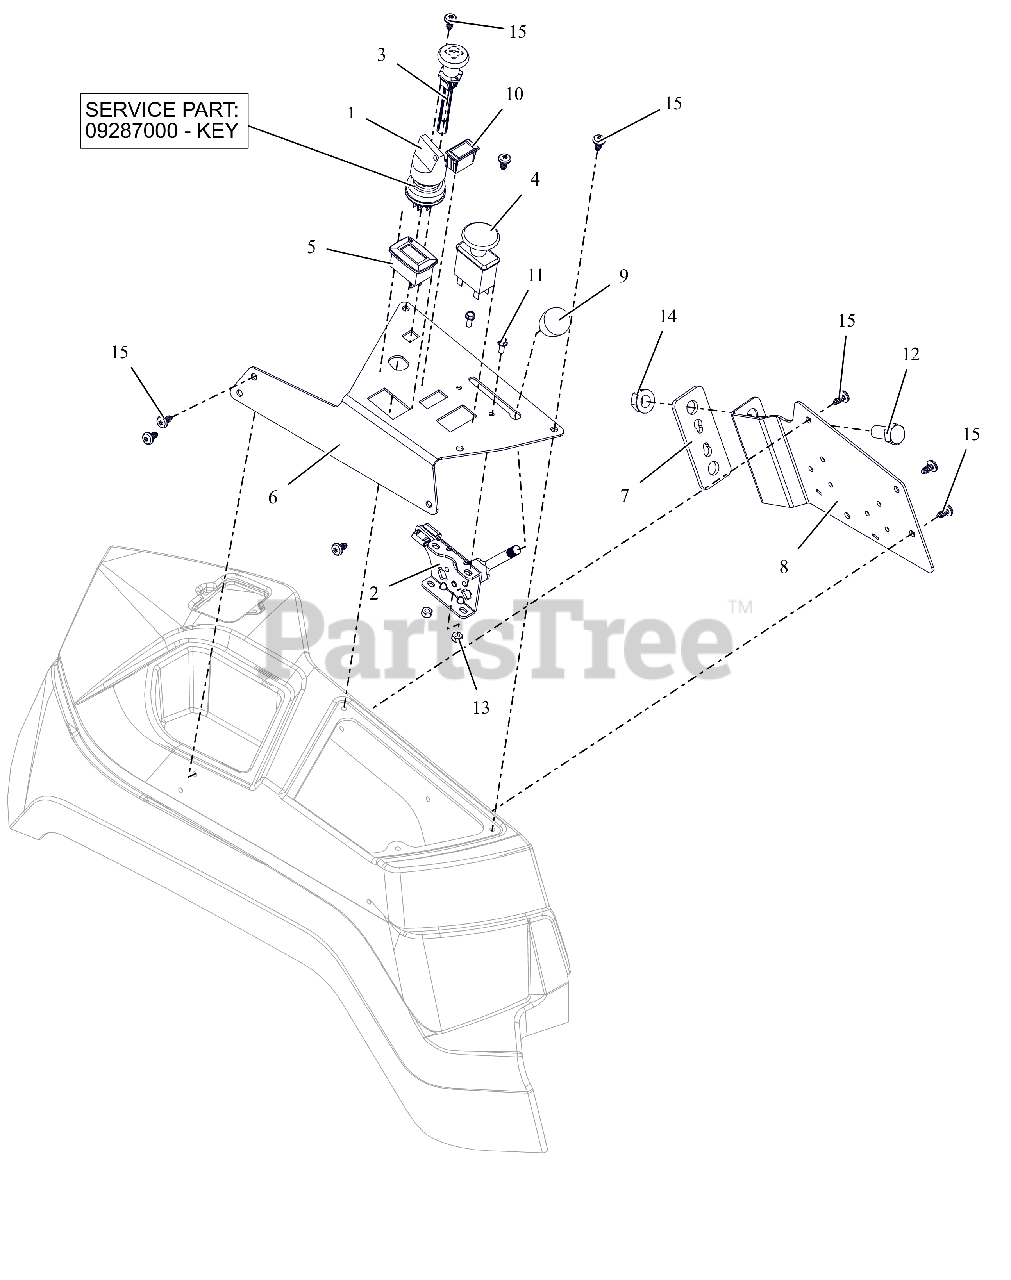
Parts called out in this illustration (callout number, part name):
1	SWITCH, IGNITION
1	KEY, W/ SHIELD
2	CABLE, PRO THROTTLE CONTROL
3	CABLE - CHOKE, SNAP-IN
4	SWITCH, CLUTCH
5	METER, HOUR W/MAINTENANCE
6	PLATE, APEX CONTROL PANEL
7	PLATE, CONTROL PANEL SPACER
8	BRKT, FENDER/RELAY MOUNTING
9	KNOB-CONTROL-BLACK .38-16X.50
10	SWITCH,BLANK
11	BLT, HWH #10-24X.50 ZCC
12	BLT, HEX .50-13X1.00 G5 ZCC
13	NUT-LK-NYL #10-24 G2 ZCC
14	NUT-LK-TOP-FLG .500-13 GF ZCC
15	SCR-PAN .25-15X.50 6L H/LZB500
